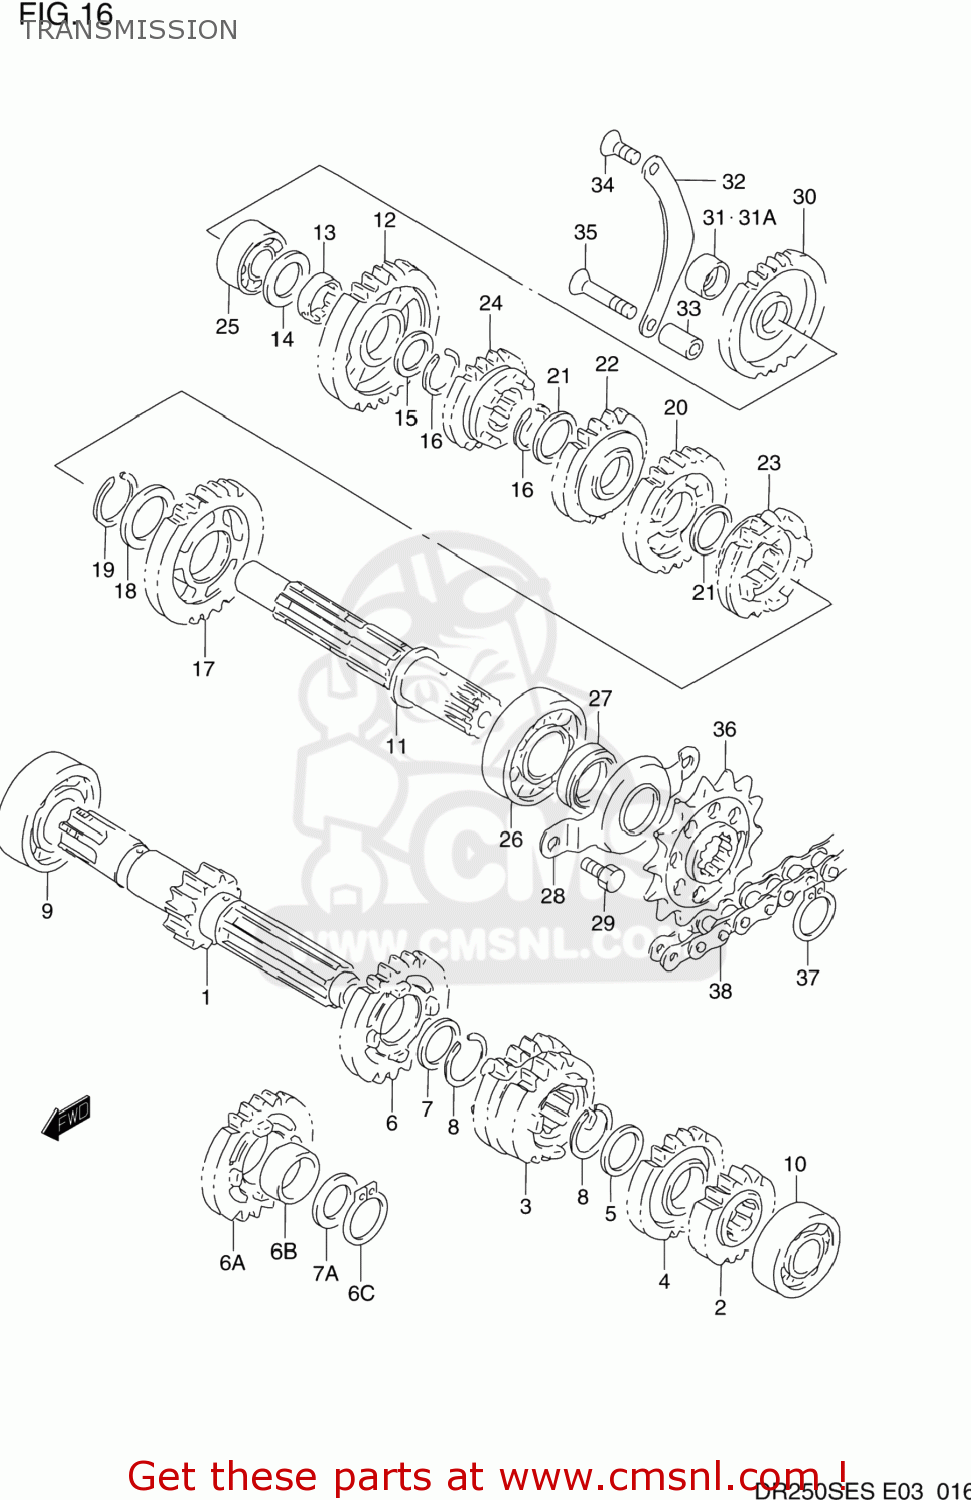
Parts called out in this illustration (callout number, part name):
1	SHAFT,COUNTER
2	GEAR,SECOND DRIVE (NT:15)
3	GEAR,THIRD/FOURTH DRIVE (NT:
4	GEAR,5TH DRIVE(NT:21)
5	WASHER
6	GEAR,SIXTH DRIVE (NT:24)
6A	GEAR,SIXTH DRIVE
6B	BUSH(22X26X9)
6C	CIRCLIP
7	SHIM
7A	WASHER,THRUST
8	CIRCLIP
9	BEARING
10	BEARING
11	SHAFT,DRIVE
12	GEAR,FIRST DRIVEN (NT:29)
13	BUSH,1ST DRIVEN GEAR
14	WASHER
15	WASHER,THRUST
16	CIRCLIP
17	GEAR,2ND DRIVEN(NT:26)
18	WASHER
19	CIRCLIP
20	GEAR,3RD DRIVEN
21	SHIM
22	GEAR,4TH DRIVEN(NT:20)
23	GEAR,FIFTH DRIVEN (NT:19)
24	GEAR,6TH DRIVEN(NT:19)
25	BEARING(17X40X17.5)
26	BEARING(22X56X16)
27	SEAL,OIL(22X34X7)
28	RETAINER,DRIVE SHAFT OIL SEAL
29	BOLT
30	GEAR,KICK STARTER IDLE(NT:27)
31	BUSH,KICK STARTER IDLE GEAR
31A	SPACER(17X25X10.5)
32	RETAINER,KICK IDLE GEAR
33	SPACER (6.5X12X21)
34	SCREW
35	SCREW
36	SPROCKET,ENGINE
37	CIRCLIP
38	CHAIN ASSEMBLY,DRIVE
